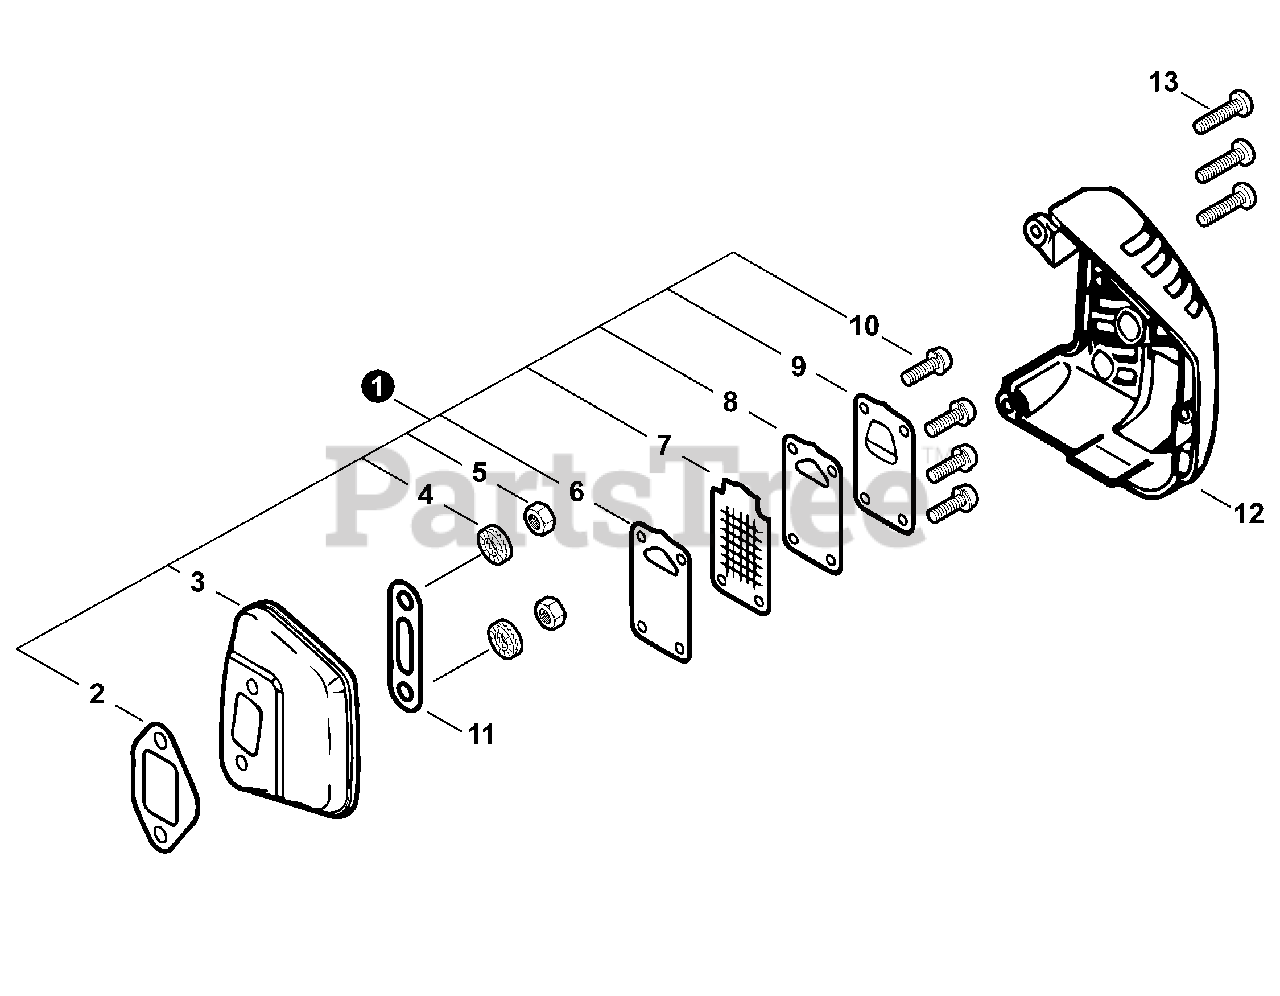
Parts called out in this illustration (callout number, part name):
1	MUFFLER KIT
2	GASKET, EXHAUST
3	MUFFLER
6	GASKET, EXHAUST
7	SCREEN, SPARK ARRESTER
8	GASKET, EXHAUST
9	OUTLET, EXHAUST
10	SCREW 4×10
11	PLATE, EYE
12	COVER, MUFFLER
13	SCREW 4×16
